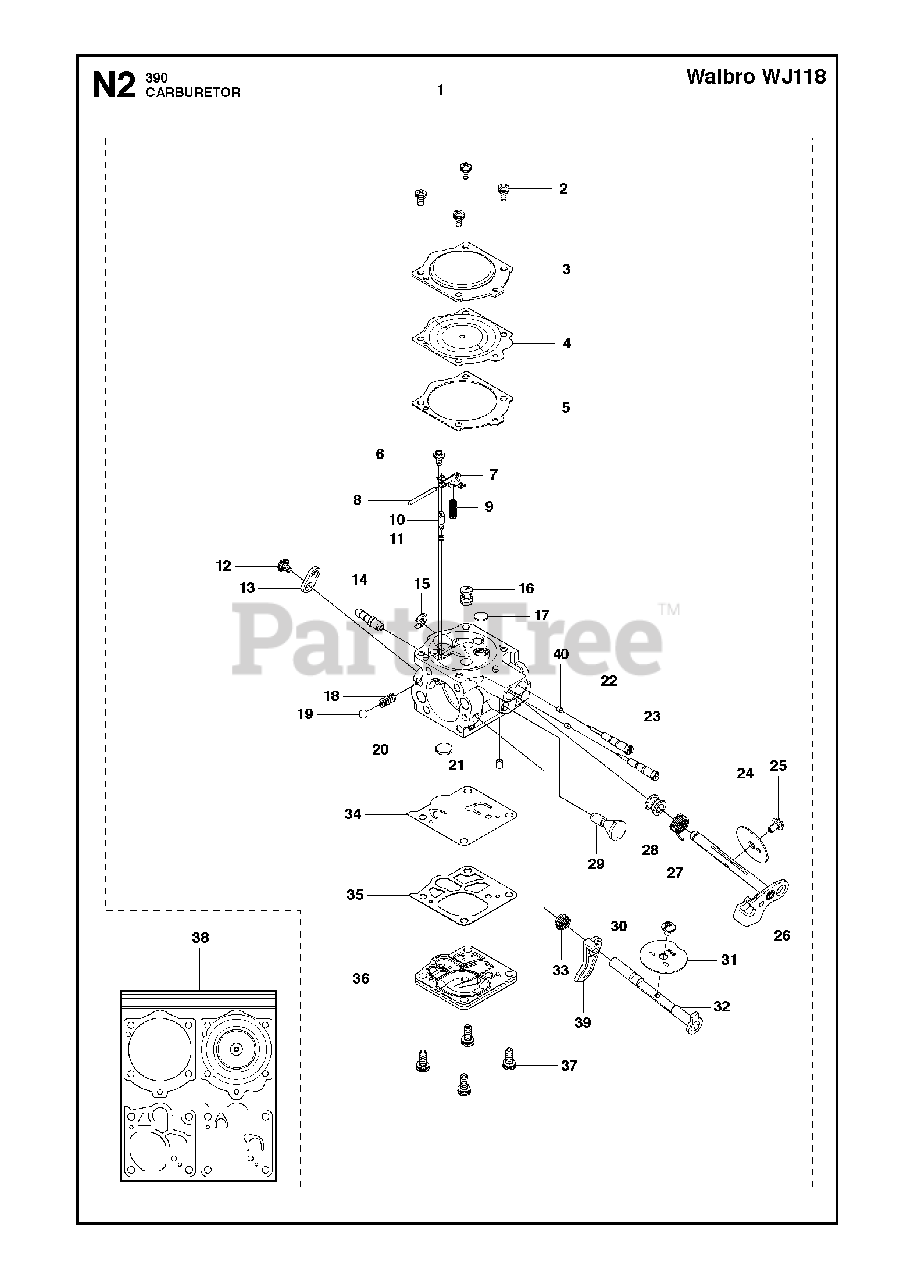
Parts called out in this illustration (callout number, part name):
1	CARBURETOR
2	RP SCREW W/ WASHER
3	DIAPHRAM COVER
4	Main Diaphragm
5	GASKET
6	SCREW
7	LEVER
8	PIN
9	SPRING
10	INLET NEEDLE
11	SEAT IN VALVE PLATED
12	SCREW
13	LEVER CHOKE
14	FITTING FUEL INLET
15	E CLIP
16	NOZZLE
17	PLUG WELCH
18	SPRING
19	BALL 394
20	FUEL INLET SCREEN
21	PLUG FRICTION
22	NEEDLE IDLE
23	NEEDLE HIGH
24	THROTTLE FLAP
25	SCREW
26	SHAFT ASSY THROTTLE
27	SPRING
28	BUSHING
29	SCREW
30	SCREW
31	CHOKE FLAP
32	SHAFT ASSY
33	SPRING CHOKE
34	DIAPHRAM PUMP
35	GASKET
36	COVER PUMP
37	SCREW W/ WASHER
38	DIAPHRAGM SET
39	LEVER
